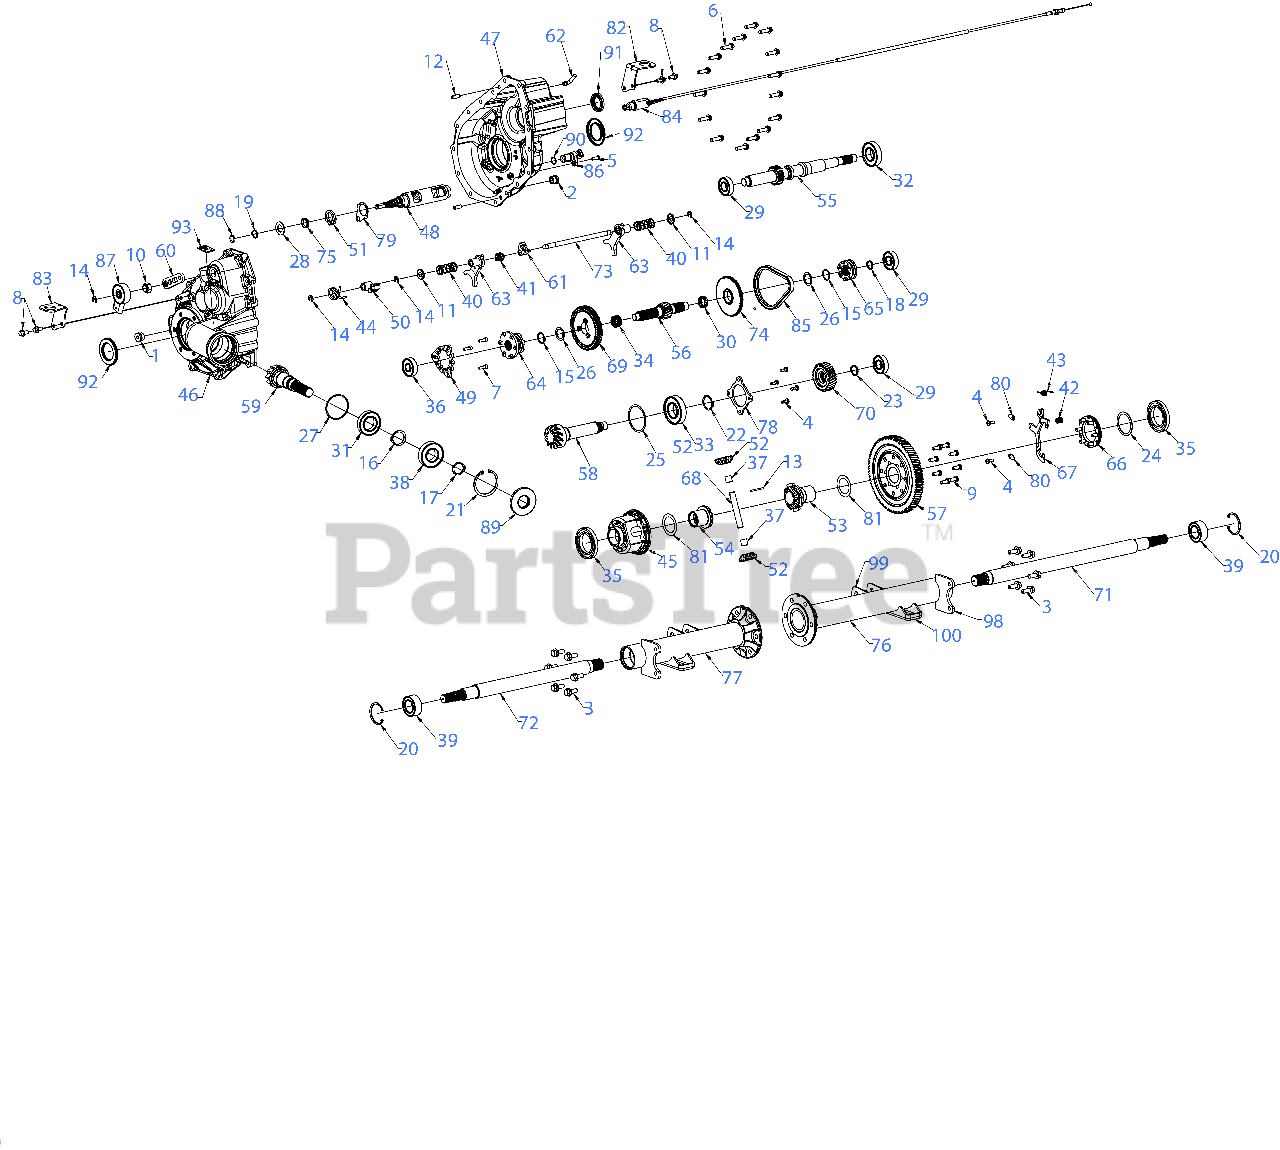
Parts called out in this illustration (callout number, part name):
1	HOLLOW HEX PLUG 3/4-16
2	HOLLOW HEX PLUG 3/4-16
3	HEX HEAD CAP SCREW 3/8-16 X 1.00
4	TORX PAN HEAD SCREW M6X1X16
5	TORX BUTTON HEAD SCREW M6X1X20
6	HEX HEAD FLANGE SCREW M8X1.25X30
7	CAP SCREW M6X1.0X18
8	HEX FLANGE HEAD SCREW M8X1.25X16
9	TORX BUTTON HEAD SCREW M8X1.25X20
10	NYLON LOCK NUT M14X2
11	CUP WASHER
12	PIN 5/16X1.00
13	DOWEL PIN 3 X 4
15	RETAINING RING
16	RETAINING RING 1.375
17	RETAINING RING IRR 7200-118
18	RETAINING RING EXTERNAL 0.787
19	RETAINING RING EXTERNAL 0.750
20	RETAINING RING INTERNAL 52MM
21	RETAINING RING INTERNAL 65MM
22	RETAINING RING EXTERNAL 1.375
23	RETAINING RING SNAP 24.00 X 1.75
24	SHIM 2.00 X 2.40
25	SHIM KIT (INCLUDES 11 SHIMS)
26	THRUST WASHER 1.30 X .995 X.065
27	THRUST WASHER 60 X 65 X 1.5
28	THRUST WASHER
29	BEARING 6204 C3
30	NEEDLE BEARING 25 X 29 X 10
31	BEARING 6007 C3
32	BEARING 6206 C3
33	BEARING 6207 C3
34	NEEDLE BEARING
35	BEARING 50 X 80 X 10
36	BEARING 6303
37	BEARING 14 X 16 X 15
38	BEARING 62/32
39	BEARING DAC 3052
40	COMPRESSION SPRING .92 X 2.00
41	COMPRESSION SPRING .46 X .73
42	COMPRESSION SPRING .54 X .44
43	TORSION SPRING LH
44	TORSION SPRING
45	DIFFERENTIAL CARRIER
48	SHIFT DRUM
49	PARK PLATE
50	DETENT PAWL
51	DETENT STAR
52	BEVEL PINION GEAR 10T
53	OUTPUT GEAR 14T
54	OUTPUT GEAR 14T
55	INPUT SHAFT 27T
56	REVERSE SHAFT 15T
57	OUTPUT GEAR 88T
58	PINION SHAFT 12T
59	GEAR SHAFT 11T
61	SHIFT COLLAR
62	VENT TUBE HOSE
63	SHIFT FORK
65	ENGAGEMENT DOG
66	ENGAGEMENT DOG
67	DIFFERENTIAL SHIFT FORK
68	DIFFERENTIAL PIN
73	SHIFT SHAFT RAIL
74	SPROCKET 52T
75	SPRING COLLAR
76	AXLE TUBE WELDMENT LH
77	AXLE TUBE WELDMENT RH
78	CENTER DRIVE BEARING COVER
80	FORK RETAINER
81	THRUST WASHER
82	MUFFLER BRACKET (LH)
83	MUFFLER BRACKET (RH)
84	DIFF LOCK CABLE
85	CHAIN .25P X .40W X 62L
86	SPEED SENSOR
87	ROTARY SWITCH 6 PIN
89	SEAL 30X72X8
91	DUAL LIP SEAL 30X47X7
92	TRIPLE LIP SEAL 40X70X7
93	LABEL
98	BRAKE CALIPER MOUNT
99	SHOCK MOUNT BRACKET
100	PERCH MOUNT BRACKET
